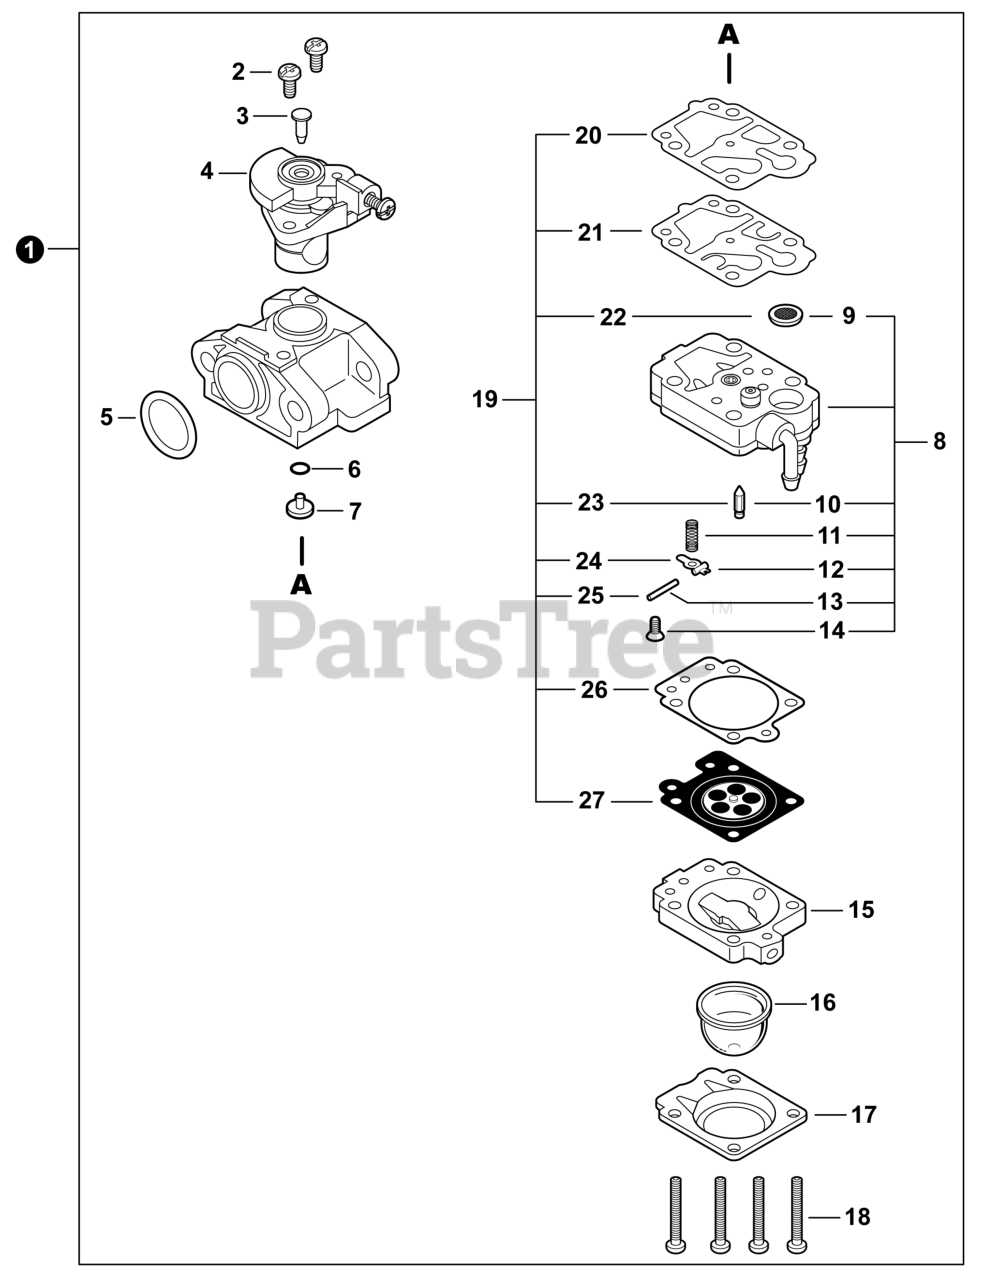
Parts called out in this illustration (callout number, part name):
1	CARBURETOR - WYL-19B
2	SCREW, THROTTLE COLLAR
4	VALVE ASSY, THROTTLE
5	O-RING 15
6	O-RING
7	JET, MAIN #37
8	BODY ASSY, PUMP
9	SCREEN, FUEL INLET
10	VALVE, INLET NEEDLE
11	SPRING, METERING LEVER
12	LEVER, METERING
13	PIN, METERING LEVER
15	BODY ASSY, PURGE
16	BULB, PURGE
17	RETAINER, PURGE BULB
19	REPAIR KIT, CARBURETOR
20	GASKET, FUEL PUMP
21	DIAPHRAGM, FUEL PUMP
22	SCREEN, FUEL INLET
23	VALVE, INLET NEEDLE
24	LEVER, METERING
25	PIN, METERING LEVER
26	GASKET, METERING DIAPHRAGM
27	DIAPHRAGM, METERING
